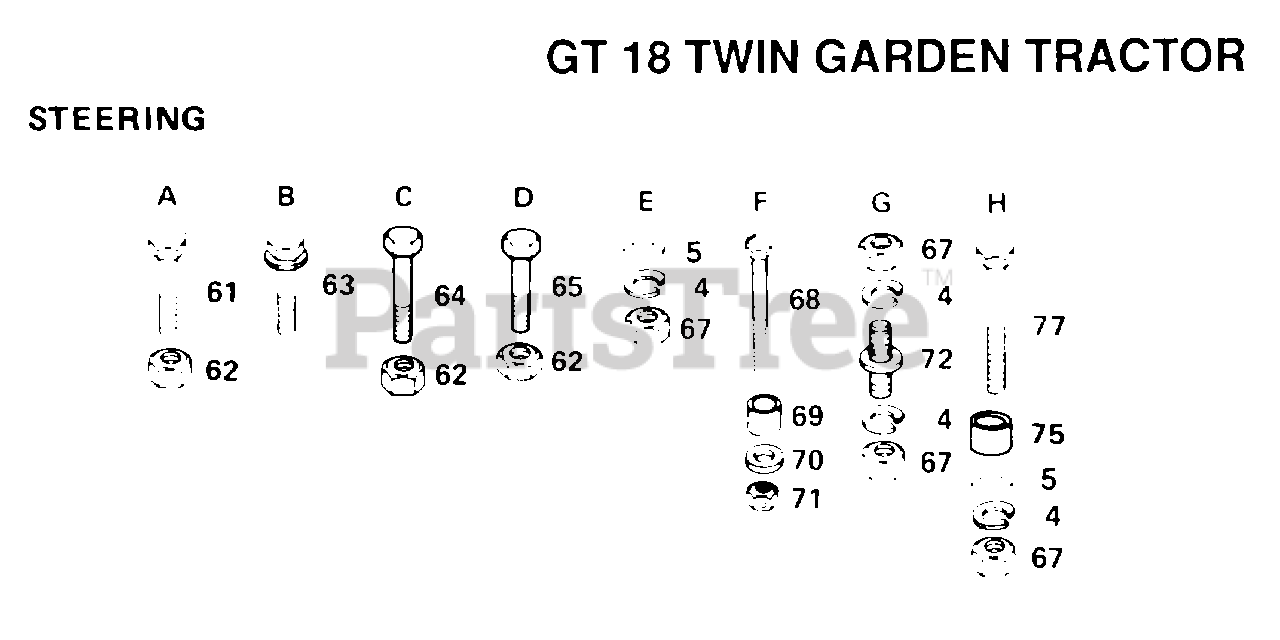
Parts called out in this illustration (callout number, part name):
4	LOCKWASHER
5	WASHER T
63	SCREW
64	BOLT
65	BOLT
67	NUT.HEX.3/8-16UNC
69	BUSHING LT
70	WASHER
75	SPLIT SPACER YTV
77	BOLT
